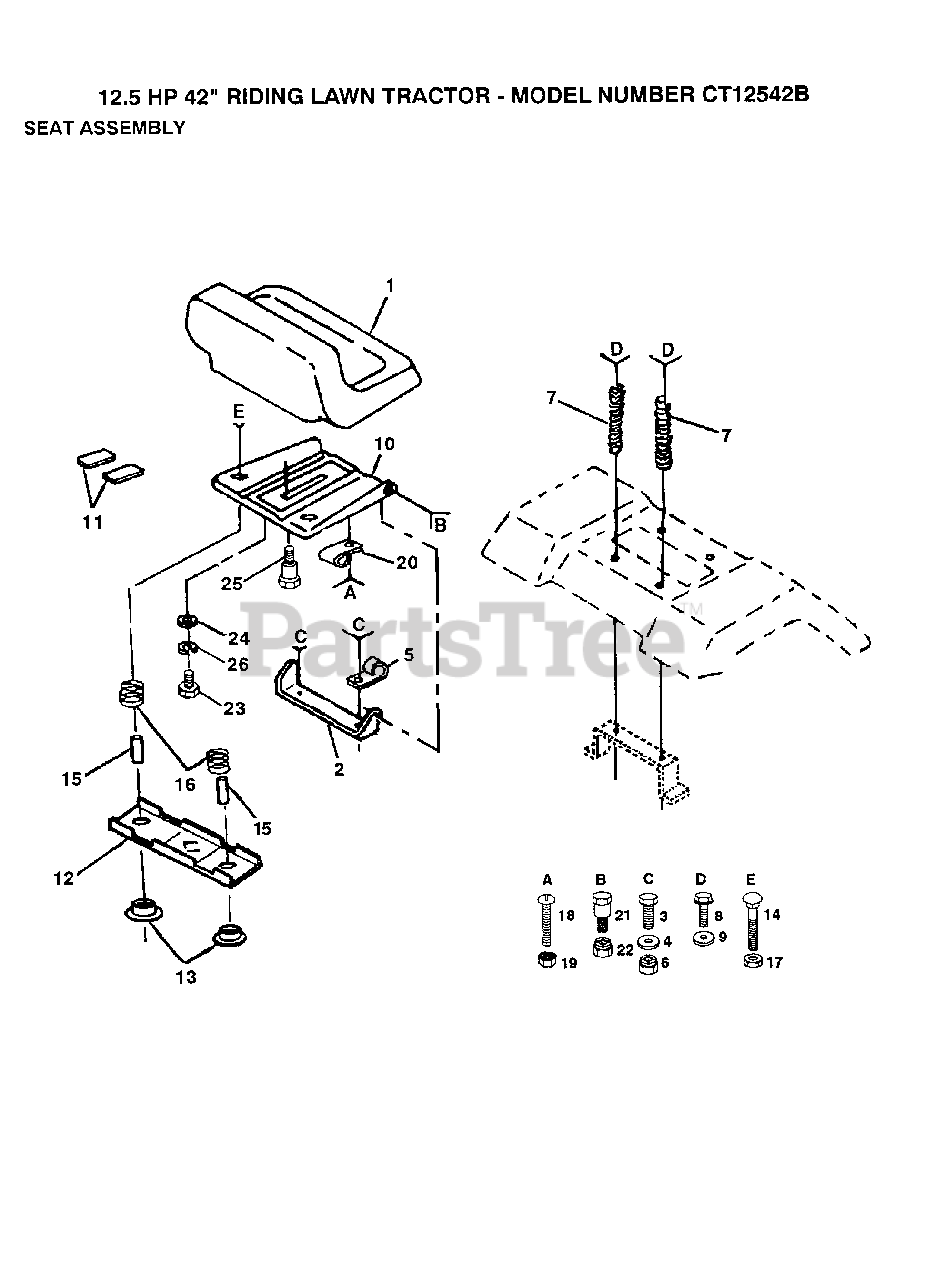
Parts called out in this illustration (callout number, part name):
4	WASHER
5	CLIP T
7	SPRING COMPRESSIO
8	SCREW GTV
9	WASHER
11	STRIP FORM
12	BRKT SWITCH
13	BUSHING
15	SPACER SPLIT
16	SPRING COMPRESSED
19	"NUT,KEPS"
23	BOLT
24	WASHER
25	"BOLT,SHOULDER"
26	LOCKWASHER
